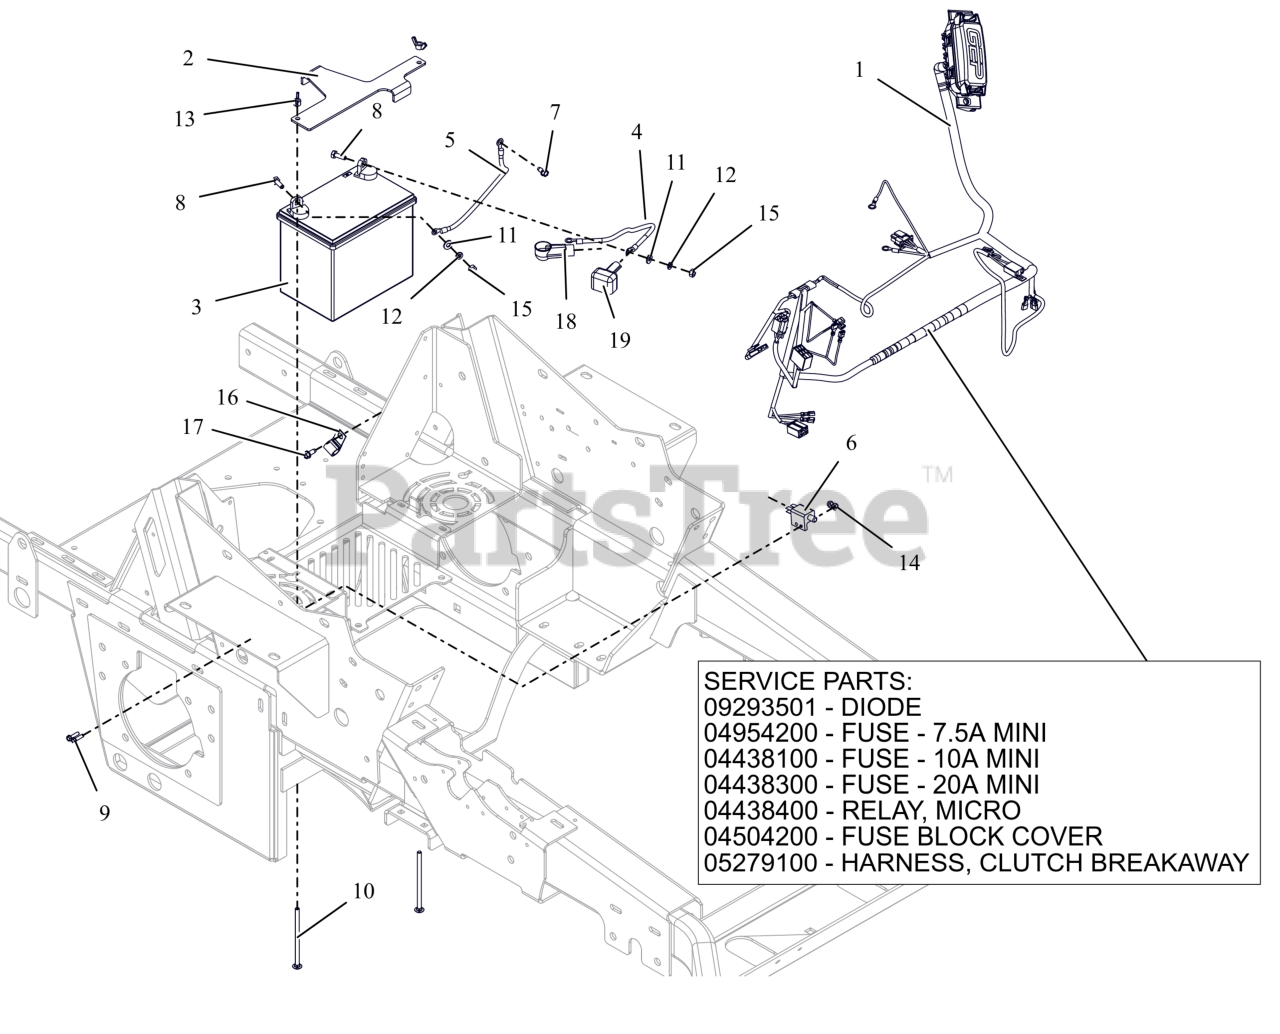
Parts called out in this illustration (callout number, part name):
1	HARNESS- WIRE PT300 MAIN
1	DIODE, CONNECTOR SHELL
1	FUSE, 7.5 AMP MINI-ATC
1	FUSE,10 AMP MINI-ATC
1	FUSE,20 AMP MINI ATC
1	RELAY,MICRO5 TERML W/RESISTOR
1	COVER, HARNESS FUSE/RELAY MOD
1	HARNESS, CLUTCH BREAKAWAY
2	HOLDDOWN- BATTERY
3	BATTERY, 300 CCA 10U1L
4	CABLE, STARTER 13.00"
5	CABLE-GROUND .25 X 13.00 X .31
6	SWITCH- DOUBLE POLE N.O./N.O.
7	SCR-TAP .25-20X.50 HWH ZCC
8	BLT, HEX .25-20X.75 G5 ZCC
9	BLT, HWH #10-24X.75 ZCC
10	BLT, RHSN .25-20X4.50 G5 ZCC
11	WSHR,FLT .281X.625X.065 ZCC
12	WSHR,LK-REG .250X.062 ZCC
13	NUT, LK-WING .25-20 ZCC
14	NUT-LK-NYL #10-24 G2 ZCC
15	NUT-STD .250-20 G2 ZCC
17	SCR,TAP .25-20X.625 HWH ZCC
18	BOOT, .65ID POS
19	INSULATOR
